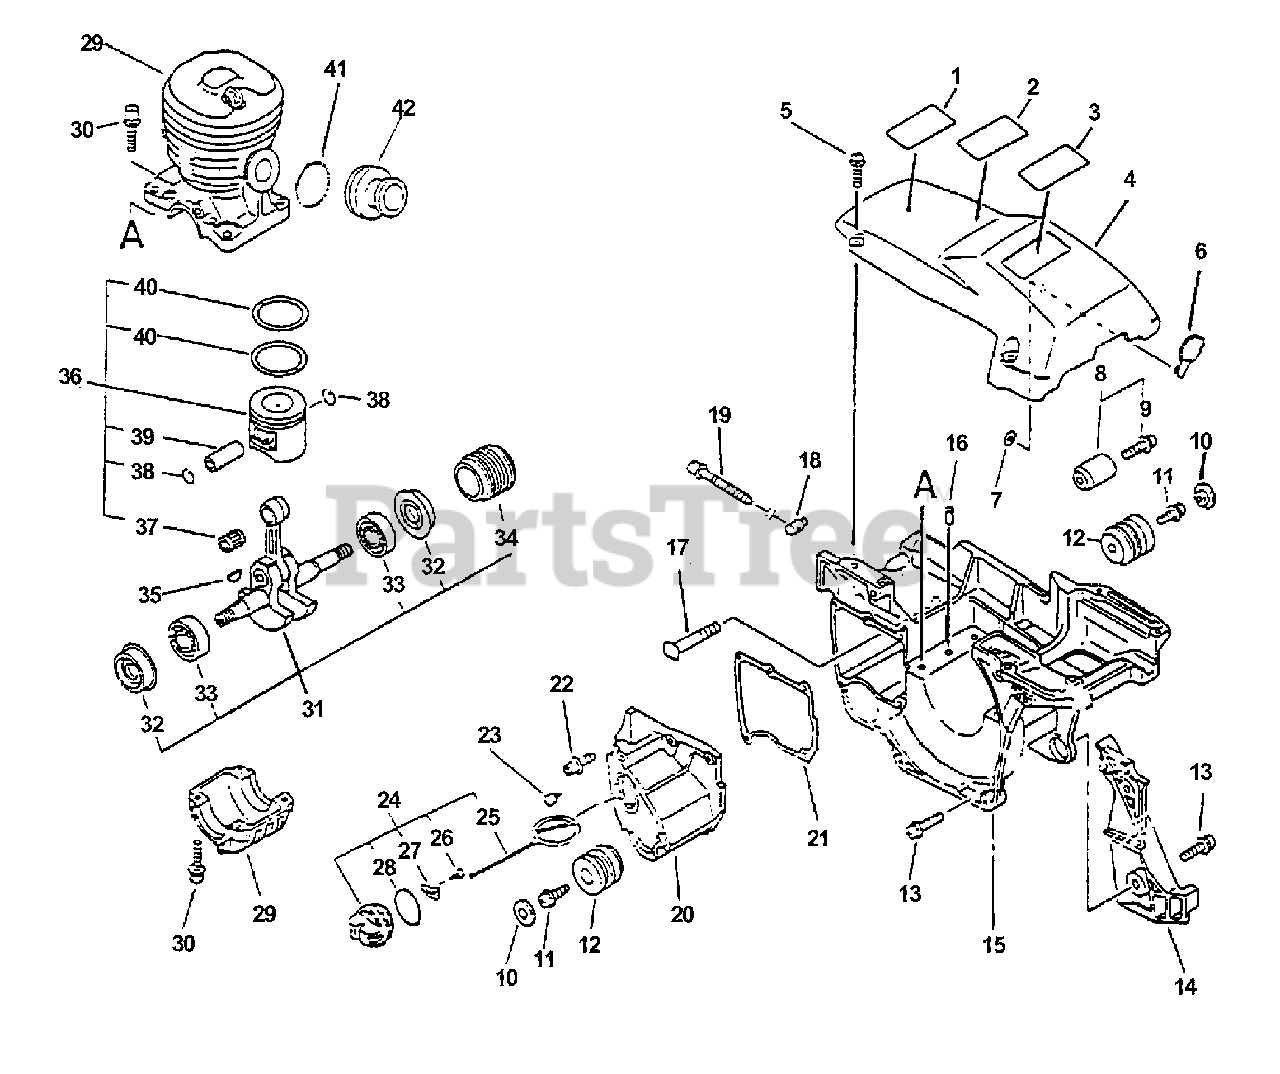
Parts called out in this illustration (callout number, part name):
1	LABEL - KICK BACK
2	LABEL - BAR & CHAIN
3	LABEL - MODEL CS-4400
4	ENGINE COVER KIT - GRAY
5	SCREW - 5
7	PUSHNUT - 4
8	CHAIN CATCHER KIT
9	SCREW - 5X18
10	CAP, CUSHION
13	SCREW - 5X16
15	COVER, ENGINE - GRAY
16	PIN - LOCATING
17	STUD, GUIDE BAR
18	TENSIONER, CHAIN
19	SCREW, TENSIONER
20	OIL TANK ASSY
21	GASKET, OIL TANK
22	SCREW - 4X16
23	VENT, TANK
24	CAP ASSY
25	CONNECTOR, CAP
26	SCREW - 3X8
27	RETAINER
28	O-RING - 25
29	CRANKCASE KIT
30	SCREW - 5X22
31	CRANKSHAFT ASSY
32	SEAL, OIL
33	BEARING, BALL - 6201
34	GEAR - WORM
35	KEY
36	PISTON KIT
37	BEARING, NEEDLE
38	RING, RETAINING
39	PIN, PISTON
40	RING, PISTON
42	ADAPTOR, INTAKE
